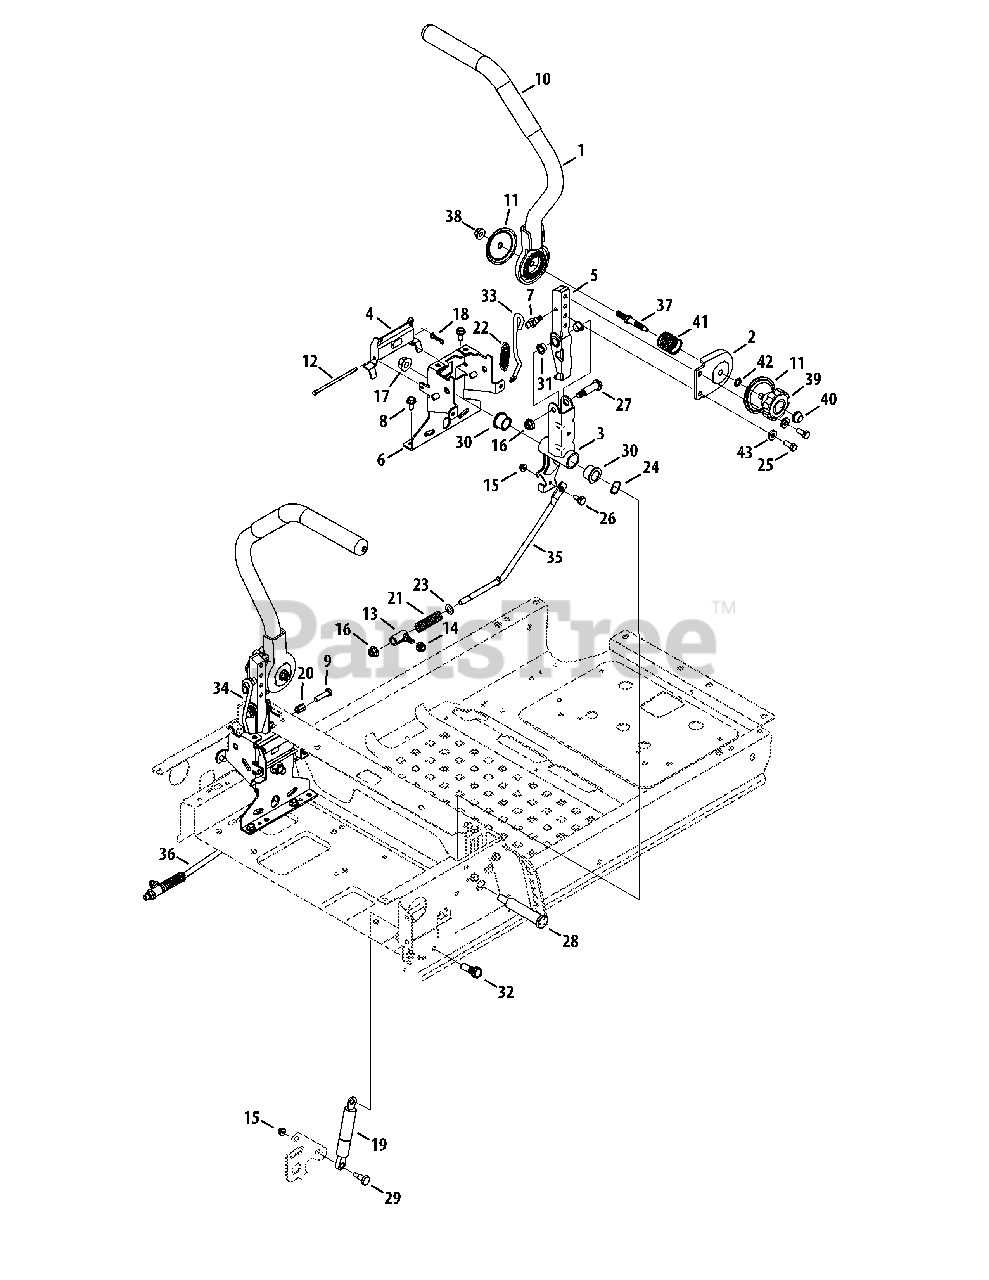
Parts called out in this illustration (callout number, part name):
1	Lapbar Lever Assembly, Outer
2	Lapbar lever Assembly, Inner
3	Lapbar Pivot Bracket
4	Brake Lever Actuator
5	Lower Arm
6	Lapbar Pivot Support Bracket
7	Screw, Shoulder Ball, 5/16-18 x .48
8	Hex Washer Screw, 5/16-18 x .750
9	Hex Cap Screw, 5/16-18 x 1.25
10	Lapbar Grip
11	Cup Adjustment Bracket
12	Pin, .188 x 4.1
13	Ferrule, 3/8 ID x .420 Shldr
14	Flange Lock Nut, 5/16-18
15	Flange Lock Nut, 1/4-20
16	Flange Lock Nut, 3/8-16
17	Flange Lock Nut, 1/2-13
18	Bow-Tie Cotter Pin
19	Dampener, .87 OD x 7.06 Lg
20	Nut, 5/16-18
21	Compression Spring, .45 x 3.215
22	Extension Spring, .56 x 2.31 x .105
23	Flat Washer, .385 x .62 x .063
24	Washer, Wave, .785 x 1.0 x .012
25	Hex Head Screw, 5/16-18 x .75 Patch
26	Shoulder Screw, .375 Dia. x .181
27	Shoulder Screw, .498 Dia. x 1.296
28	Shoulder Screw, .75 x 3.25 x 1/2-13
29	Shoulder Screw, .395 Dia. x .56
30	Bearing, .75 x 1.00 x .73
31	Flange Bearing, .500 x .627
32	Shoulder Screw, .395 Dia. x .83
33	Lapbar Detent Rod, RH
34	Lapbar Detent Rod, LH
35	Hydro Control Rod, RH
36	Hydro Control Rod, LH
37	Adjustment Stud
38	Jam Lock Nut, 3/8-16
39	Fluted Knob, 3/8-16
40	Push Cap, .250
41	Compression Spring, 1.245 x 1.275
42	Lock Washer, 3/8
43	Flat Washer, .344 x .750 x .120
